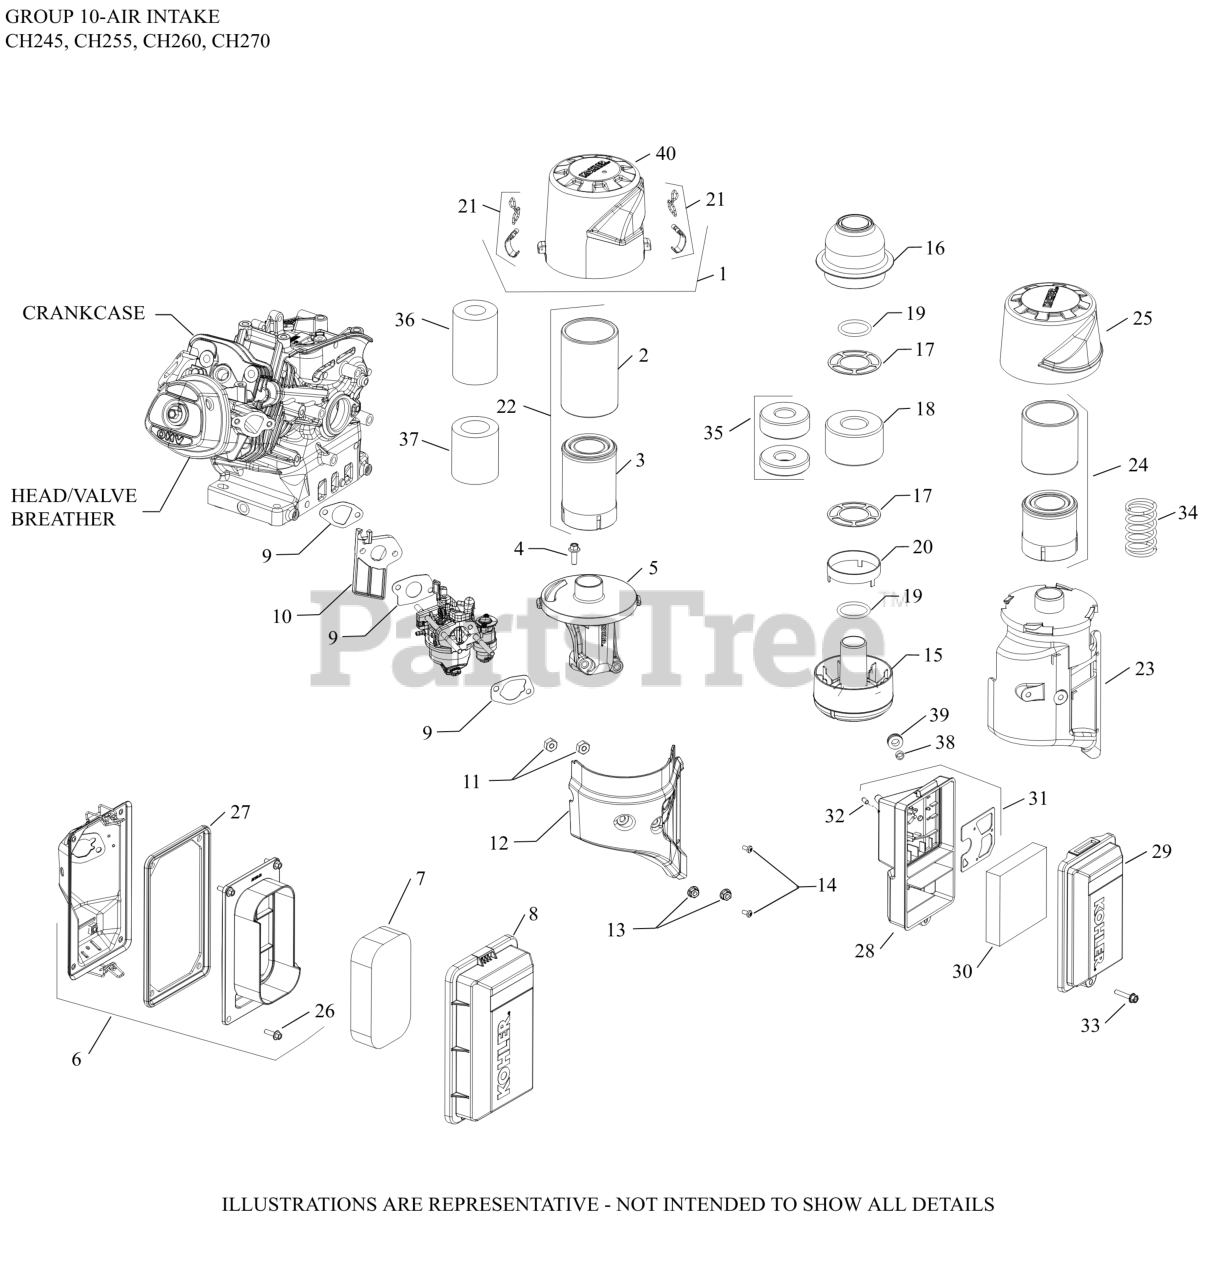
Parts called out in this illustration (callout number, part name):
1	COVER, AIR CLEANER ASSEMBLY
2	ELEMENT, PRE-CLEANER - USE 17 083 12-S
3	ELEMENT, AIR FILTER
4	SCREW, M6 X18
5	KIT, AIR CLEANER BASE ASSEMBLY
11	NUT, HEX (M6 THREAD, M8 BODY)
12	COVER, AIR CLEANER BASE SHIELD
14	SCREW,COVR TO BLWR HOUSING
21	KIT, LATCH CLIP
